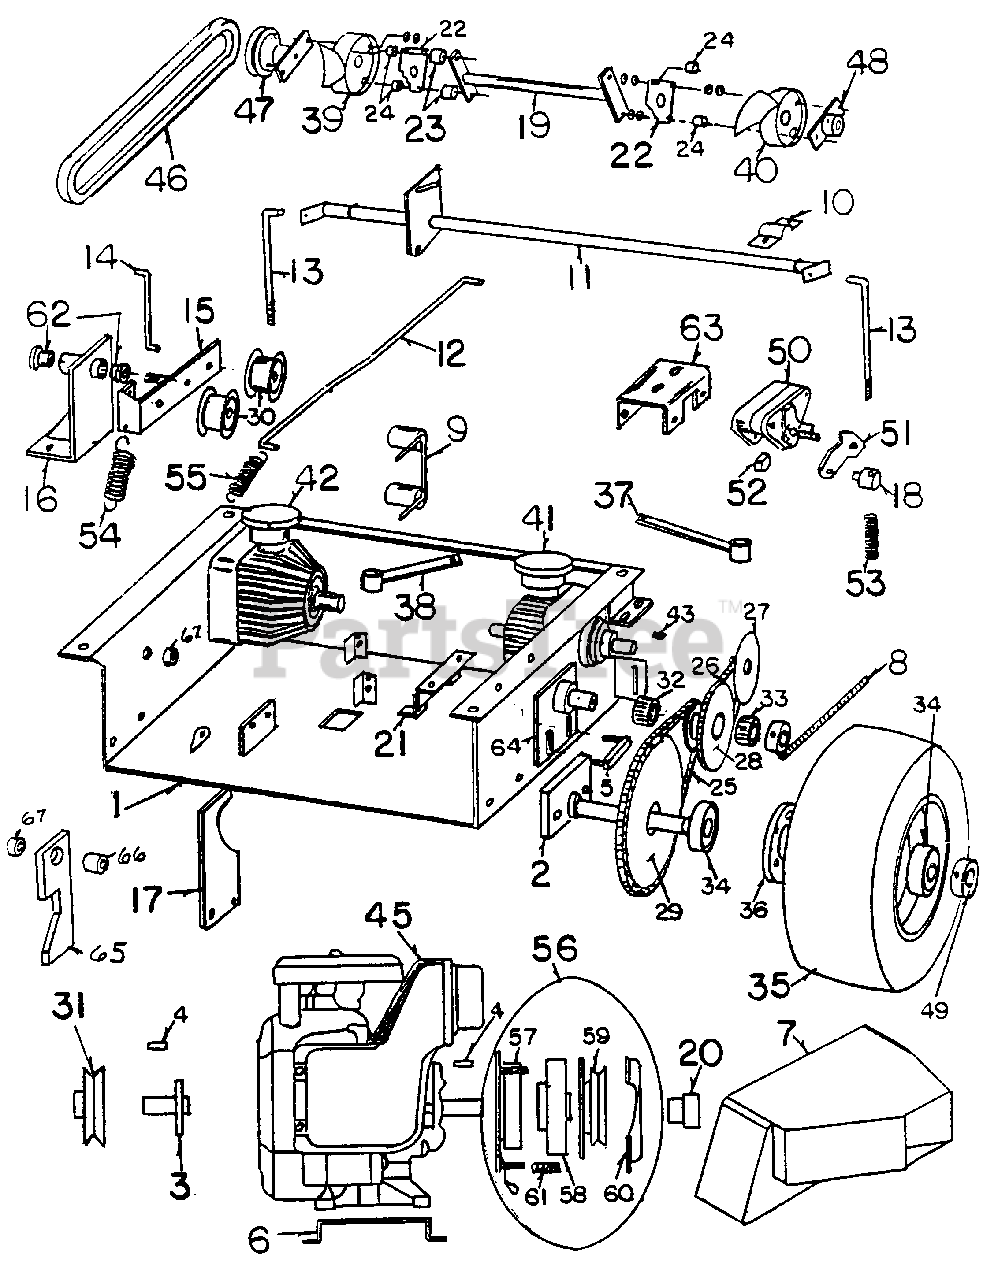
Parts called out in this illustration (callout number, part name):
1	Base
2	Axle, Drive Wheel
4	Key Stock
6	11 H.P. Adapter Plate
7	Air Duct
8	L.H. 1 R.H. Support Collars
10	Bearing, Clutch & Brake Cross Rod
11	Clutch & Brake Cross Rod
12	Brake Pedal Rod
15	Clutch Pulley Mount
16	Clutch Bracket
17	Belt Retainer, Engine
18	Caliper Rod Collar
20	Electric Clutch Retainer
21	Electric Clutch Stop
22	Drive Plate
25	Chain, Final Drive
26	Chain, Primary Drive
27	Sprocket Transmission & Disc Brake
28	Sprocket, Primary Drive
29	Sprocket, Final Drive
30	Idler Pulley
31	Pulley, Engine
32	Short Bearing, Idler Sprocket
33	Long Bearing, Idler Sprocket
34	Bearing, Drive Wheel
35	Drive Wheel Assembly
36	Wheel Hub
37	Arm, Transmission R.H.
38	Arm, Transmission L.H.
39	C.W. Fan R.H. Side
40	C.C.W. Fan L.H. Side
41	Transmission L.H. C.W.
42	Transmission R.H. C.C.W.
43	Transmission Key
45	Briggs & Stratton 18 H.P.
46	Belt, Transmission
47	Pulley, Transmission with Drive Plate Bar
48	Hub, Transmission with Drive Plate Bar
49	Set Collar, Drive Wheel
50	Brake Caliper
51	L.H. 900-5566 R.H. 1 ea. Caliper Lever
53	Caliper Spring
55	Brake Pedal Spring
56	Electric Clutch
57	Electric Clutch Coil
58	Electric Clutch Coil Housing
59	Clutch Armature
63	Caliper Bracket
64	Shaft Idler Sprocket
65	Forward Nose Down Lock
66	Bushing Long
67	Bushing Short
